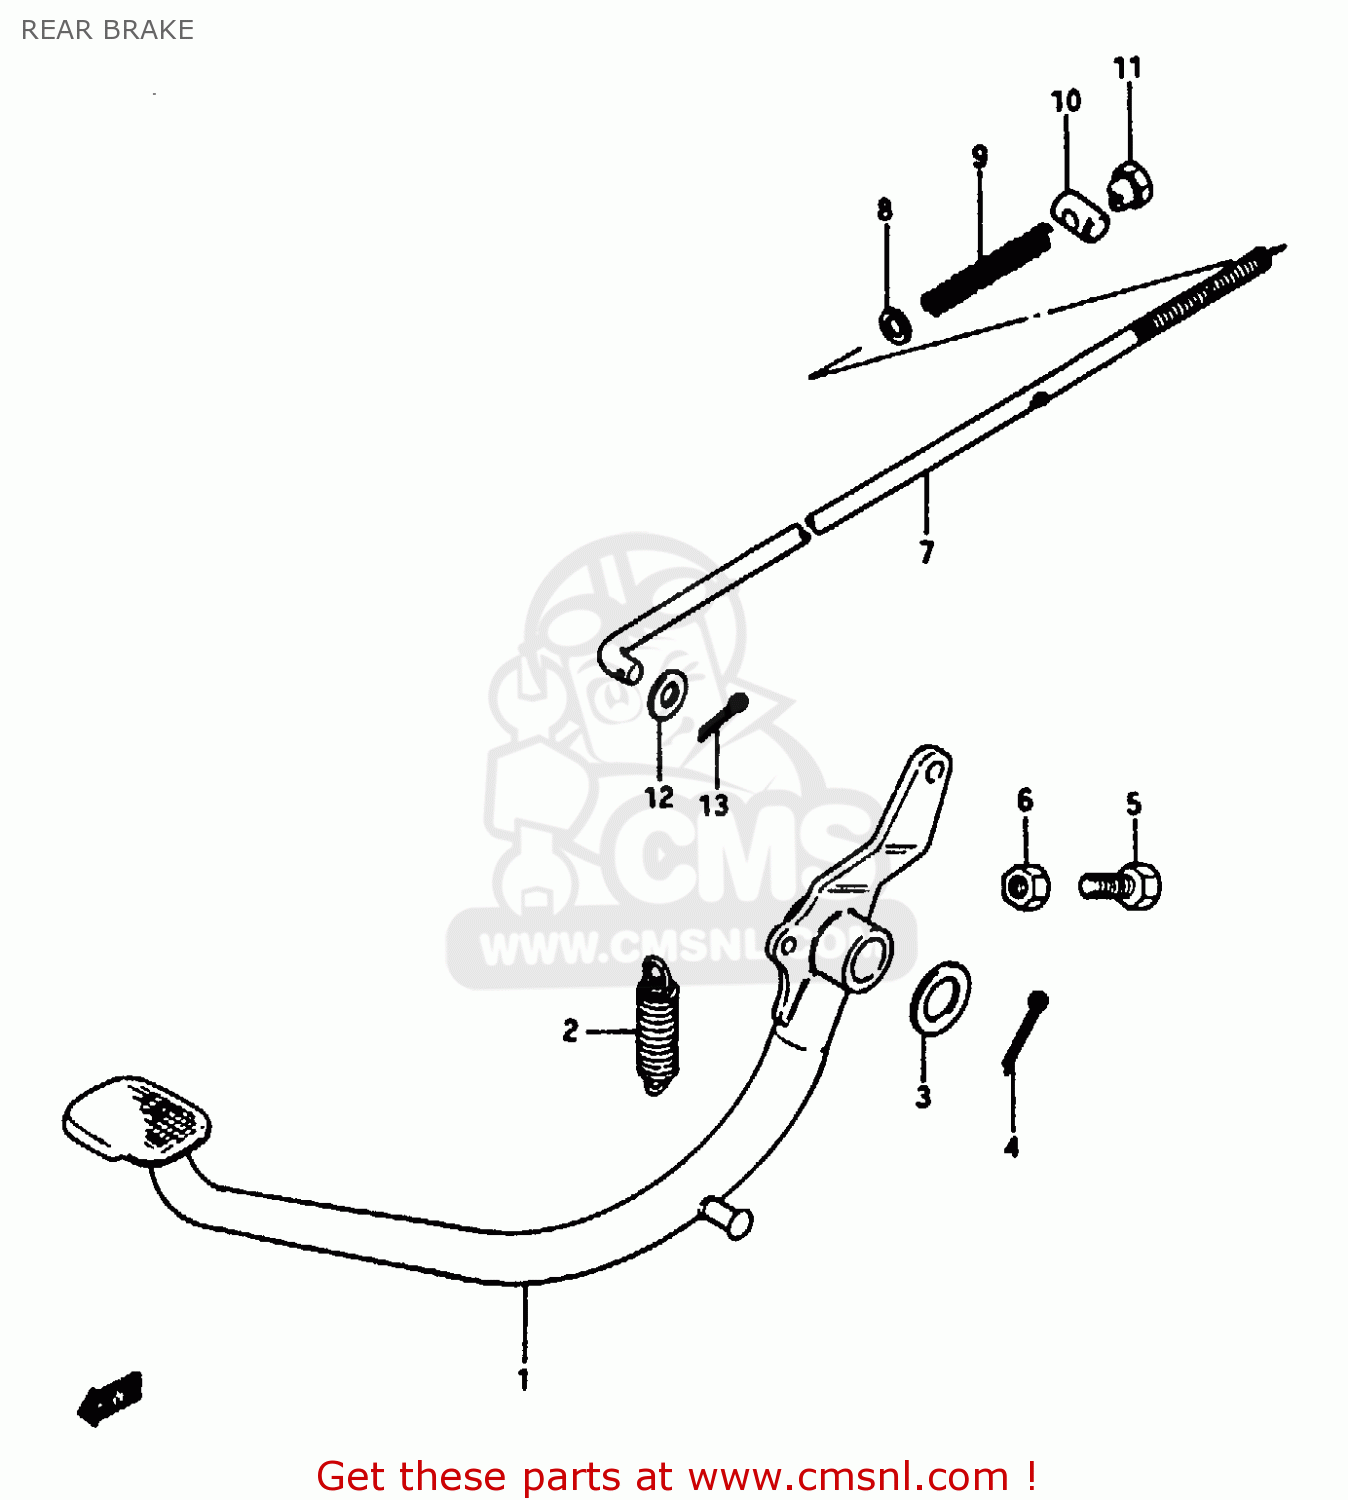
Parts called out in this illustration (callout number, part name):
1	PEDAL,BRAKE
2	SPRING
3	WASHER(15.5X26X2.3)
4	COTTER PIN
5	SCREW(6X23)
6	NUT 6MM
7	ROD ASSY,RR BRAKE
8	WASHER
9	SPRING
10	PIN
11	NUT (6MM)
12	WASHER
13	PIN 20X20
